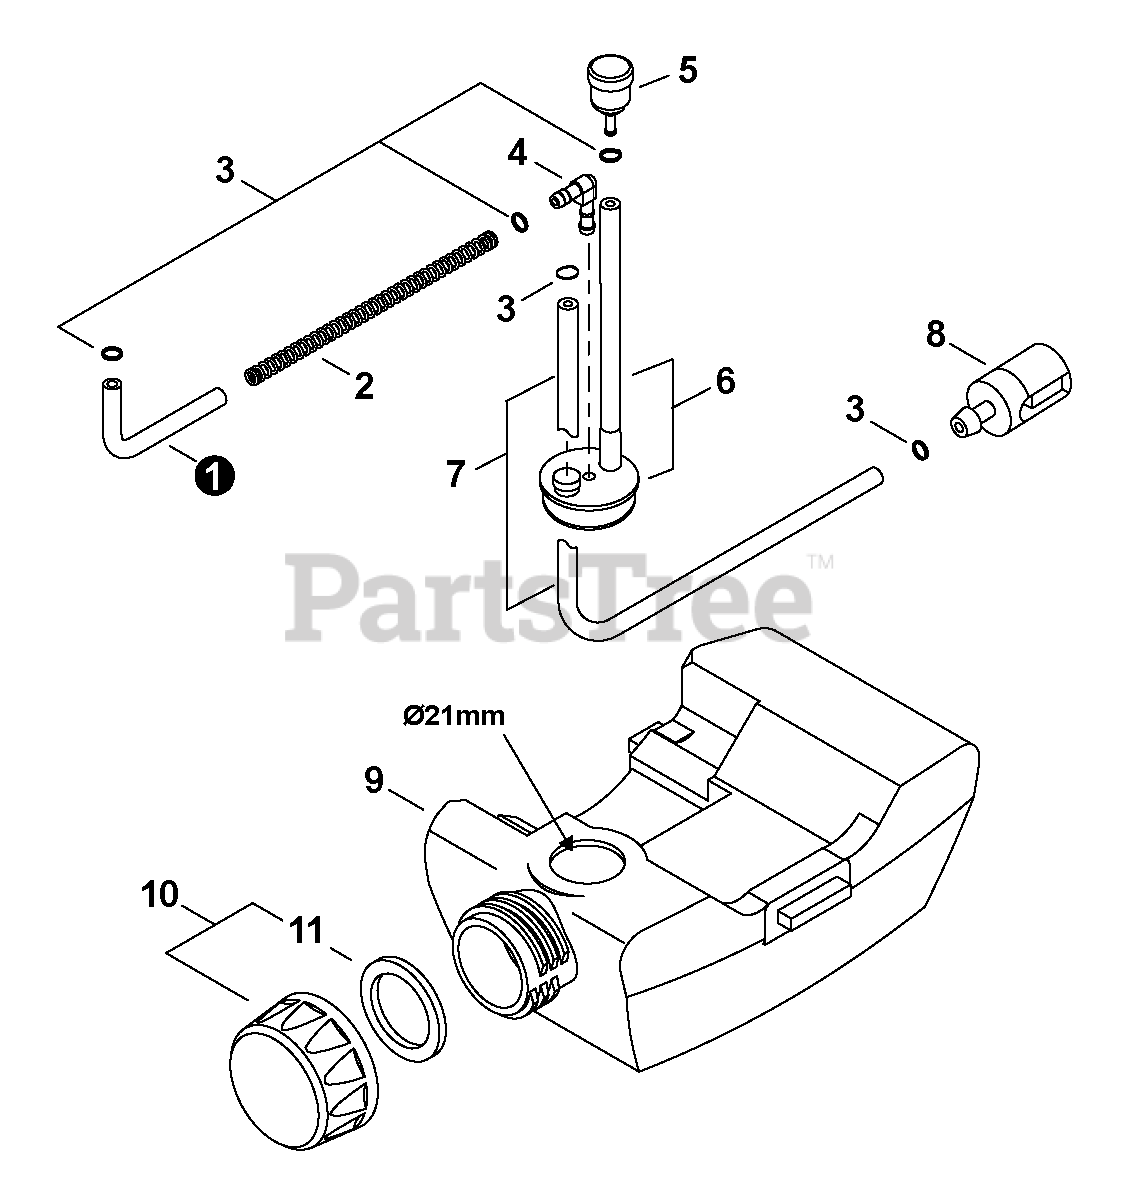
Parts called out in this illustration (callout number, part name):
1	Pipe, Fuel Return
3	Clip dia.6
4	Connector, Pipe
5	Vent Assy
6	Grommet
7	Pipe, Fuel
8	Filter, Fuel
9	Tank, Fuel
10	Cap Assy, Fuel
11	Gasket, Fuel Cap
